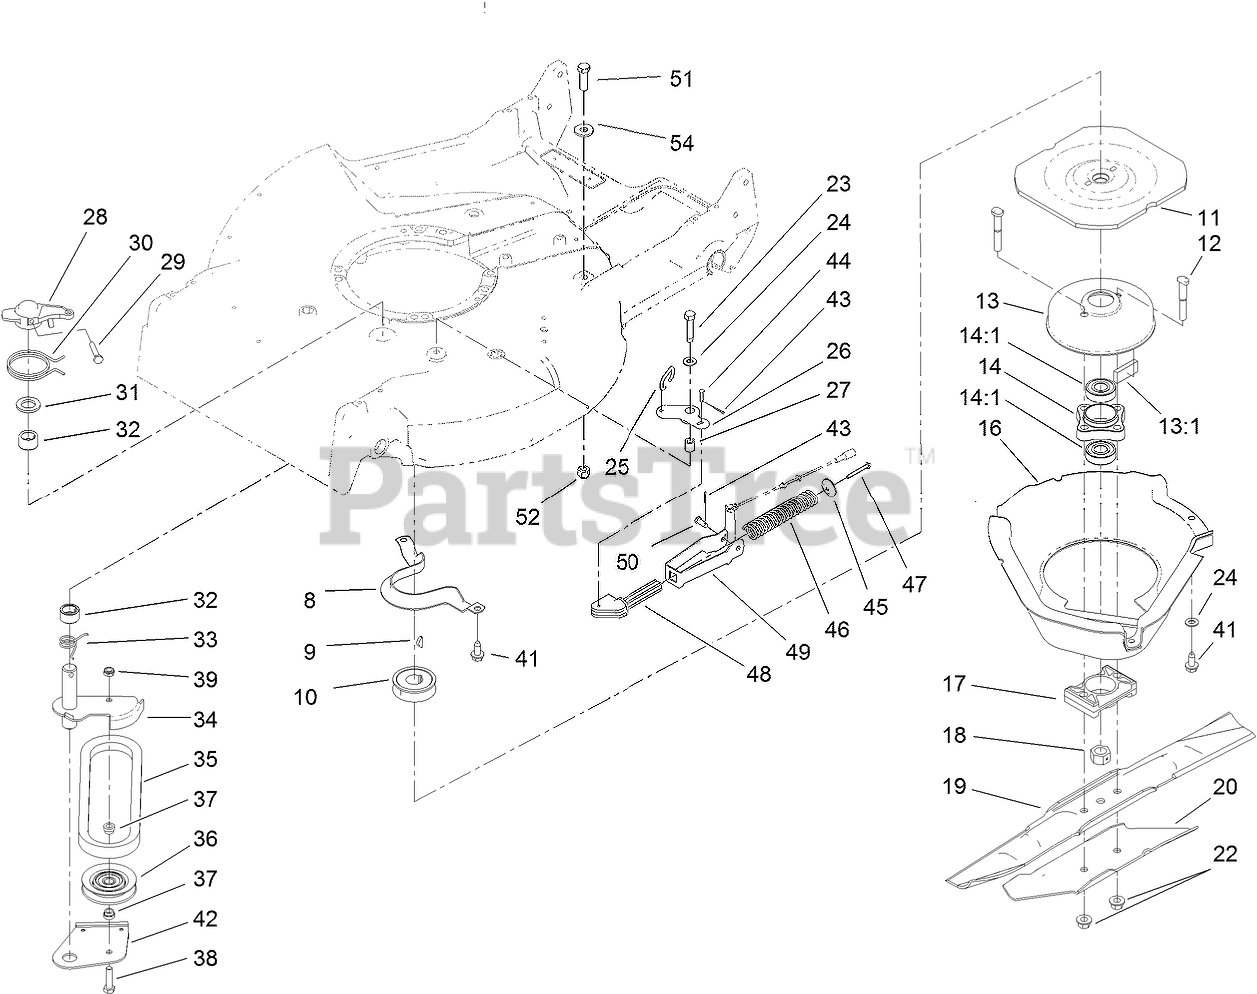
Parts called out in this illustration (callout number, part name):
8	BRACKET-GUIDE, BELT
9	KEY-WOODRUFF
10	PULLEY-DRIVER
11	FLYWHEEL-BBC
12	BOLT-BLADE
13	BRAKE DRUM ASM
13:1	DAMPENER-VIBRATION
14	HUB ASM
14:1	BEARING-BALL
16	SHIELD
17	SPACER-BLADE
18	NUT-BLADE
19	BLADE-21 INCH
20	STIFFENER-BLADE
22	NUT-LOCK
23	SCREW-HH
24	WASHER-PLAIN
25	LINK-CONTROL
26	BELLCRANK
27	SLEEVE-BELLCRANK
28	LEVER
29	SCREW-HH
30	SPRING-TORSION
31	WASHER
32	BEARING
33	SPRING-TORSION
34	ARM-IDLER
35	V-BELT
36	PULLEY-IDLER
37	SPACER-PULLEY, IDLER
38	SCREW-HH
39	NUT-LOCK, NI
41	SCREW-HWHTF
42	BRAKE PLATE ASM
43	PIN-COTTER
44	PIN-SPRING
45	RETAINER-SPRING
46	SPRING
47	SCREW-HWHTF
48	GUIDE-SPRING
49	BRACKET-SPRING
50	PIN-CABLE
51	SCREW-HH
52	NUT-LOCK, NI
54	WASHER-HARDENED
